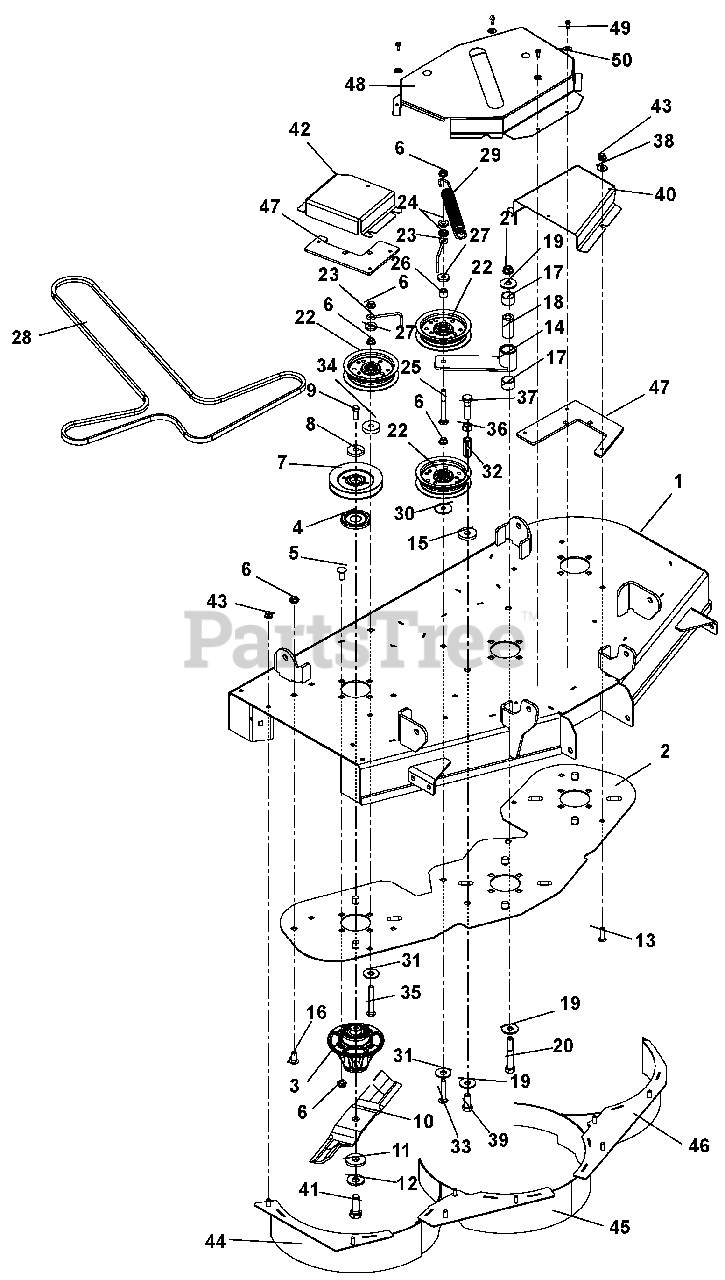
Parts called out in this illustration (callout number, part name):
1	XL-42 DECK KIT WITH DECALS
2	DOUBLER PLATE, 42 XL
3	SPINDLE ASSEMBLY
4	DUST CAP
5	@BLT-RDHDSQNK .38-16X1.25 G5YZ
5	@BLT-RDHDSQNK .38-16X1.50 G5YZ
6	@NUT-LK-NYL-FLG .38-16 YWZC
7	PULLEY, SPINDLE
8	WSHR,FLT STL.406X1.50X.245YWZC
9	BLT-HEX .38-16X1.0 GR8 YZ EP30
10	BLADE, MULCH 14.50"
11	WSHR-FLT .640X1.75X.250
12	WSHR-BLVL .669X1.535X.138
13	BLT-SERHFWH .312-18X.50 YWZC
14	WELDMENT, IDLER ARM
15	WSHR-FL-STL .515X1.625X.250 YZ
16	@BLT-RDHDSQNK .38-16X1.00 G5YZ
17	BRG, 1.00 X 1.12 X .75
18	BSHG, SPCR .502X.997X2.03 PM
19	WSHR-FL-STL.511X1.441X.125 YWZ
20	@BLT-HEX .50-13X3.50 GR5 YWZC
21	@NUT-LK-NYL-FLG .50-13 YWZC
22	ASM, IDLER 4"
23	BELT FINGER
24	BSHG-FLG .406X.88X.270X.140
25	@BLT-RDHDSQNK .38-16X3.50 G5YZ
26	BSHG-SLV .391X.688X.52 PM
27	WSHR-FL-STL .406X1.00X.188 YWZ
28	V-BELT, HA-WRAPPED
29	EXTENSION SPRING
30	WSHR-FL-STL .390X1.5X.125 YWZC
31	PLATE,IDLER MNT REINFORCEMENT
32	NUT, COUPLING 1/2-13X1.75 YWZC
33	@BLT-RDHDSQNK .38-16X2.25 G5YZ
34	SPACER, .39 X 1.50 X .380
35	@BLT-RDHDSQNK .38-16X3.50 G5YZ
36	@NUT-HEX .50-13 YWZC
37	@BLT-HEX .50-13X2.00 GR5 YWZC
38	@WSHR-FL-STL.38X.875X.083 YWZC
39	@BLT-HEX .50-13X1.25 GR5 YWZC
40	BELT COVER, LEFT
41	BLT-HEX .62-18X1.75 GR8 YWZC
42	BELT COVER, RIGHT
43	@NUT-LK-NYL-FLG .31-18 YWZC
44	WMT, 42 MULCH BAFFLE (RH)
45	WMT, 42 MULCH BAFFLE (CTR)
46	WMT, 42 MULCH BAFFLE (LH)
47	BRKT, BELT COVER MOUNT - LHS
47	BRKT, BELT COVER MOUNT - RHS
48	GUARD, 42" ZOOM/ZT CE BELT
49	SCR-TAP .25-20X.50 LGHWH TR YZ
50	NUT-PUSH .25X.50 O.D.
